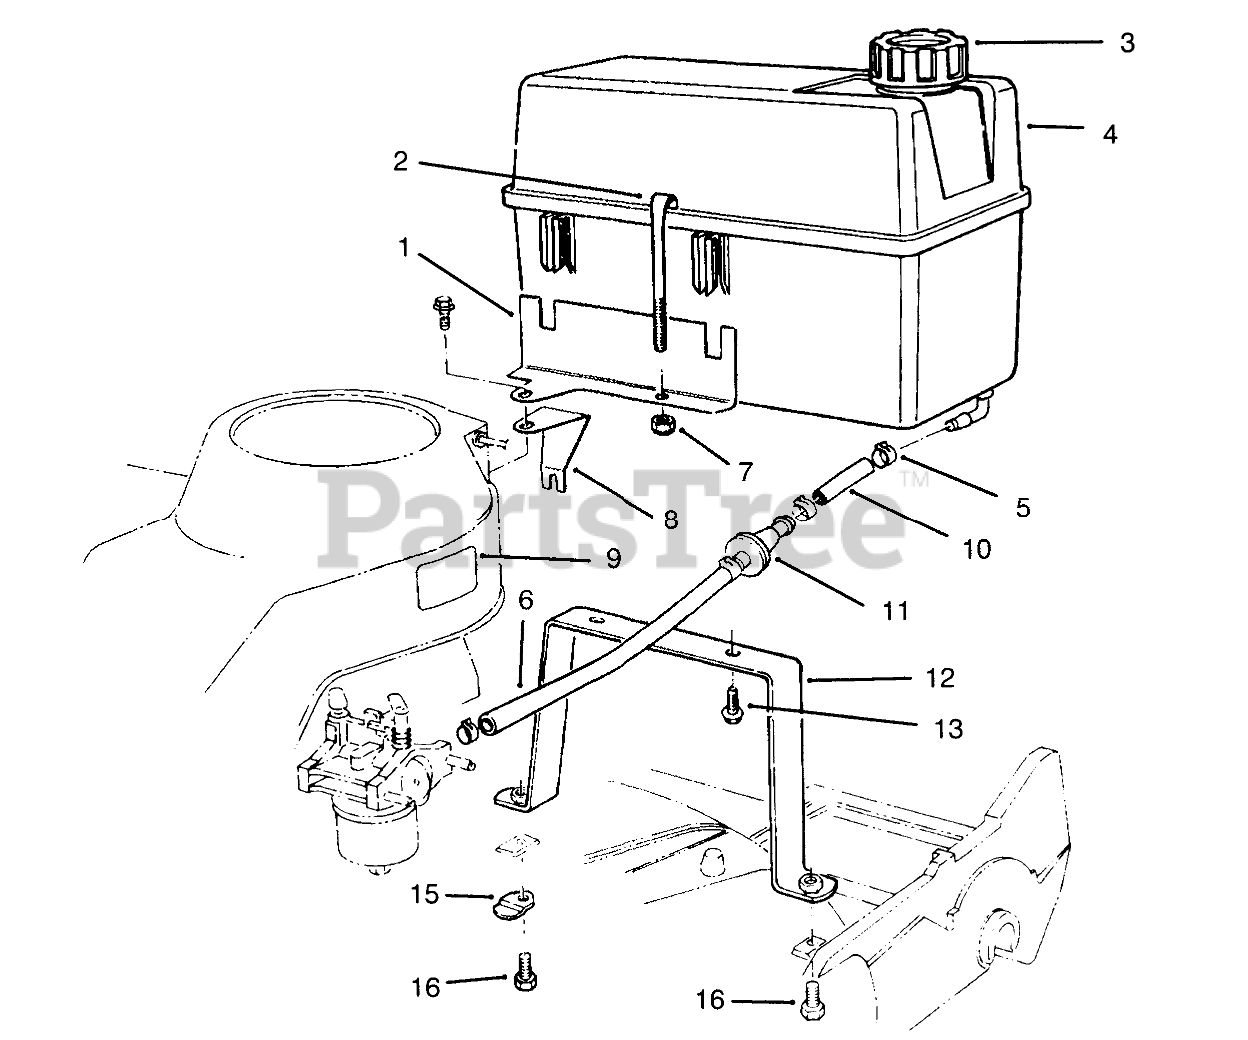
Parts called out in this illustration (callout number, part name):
1	Bracket Tank
2	RETAINER - FUEL TANK
3	GAS CAP ASM
4	Tank-Gas
5	CLAMP-FUEL LINE
6	HOSE-FUEL
7	NUT-LOCK, NI
8	Support-Bracket
9	DECAL-FUEL, 2 CYCLE
10	LINE-GAS
11	FILTER-FUEL
12	Base-Tank
13	SCREW-HWH
15	SHIELD-RETAINER
16	SCREW-HH
